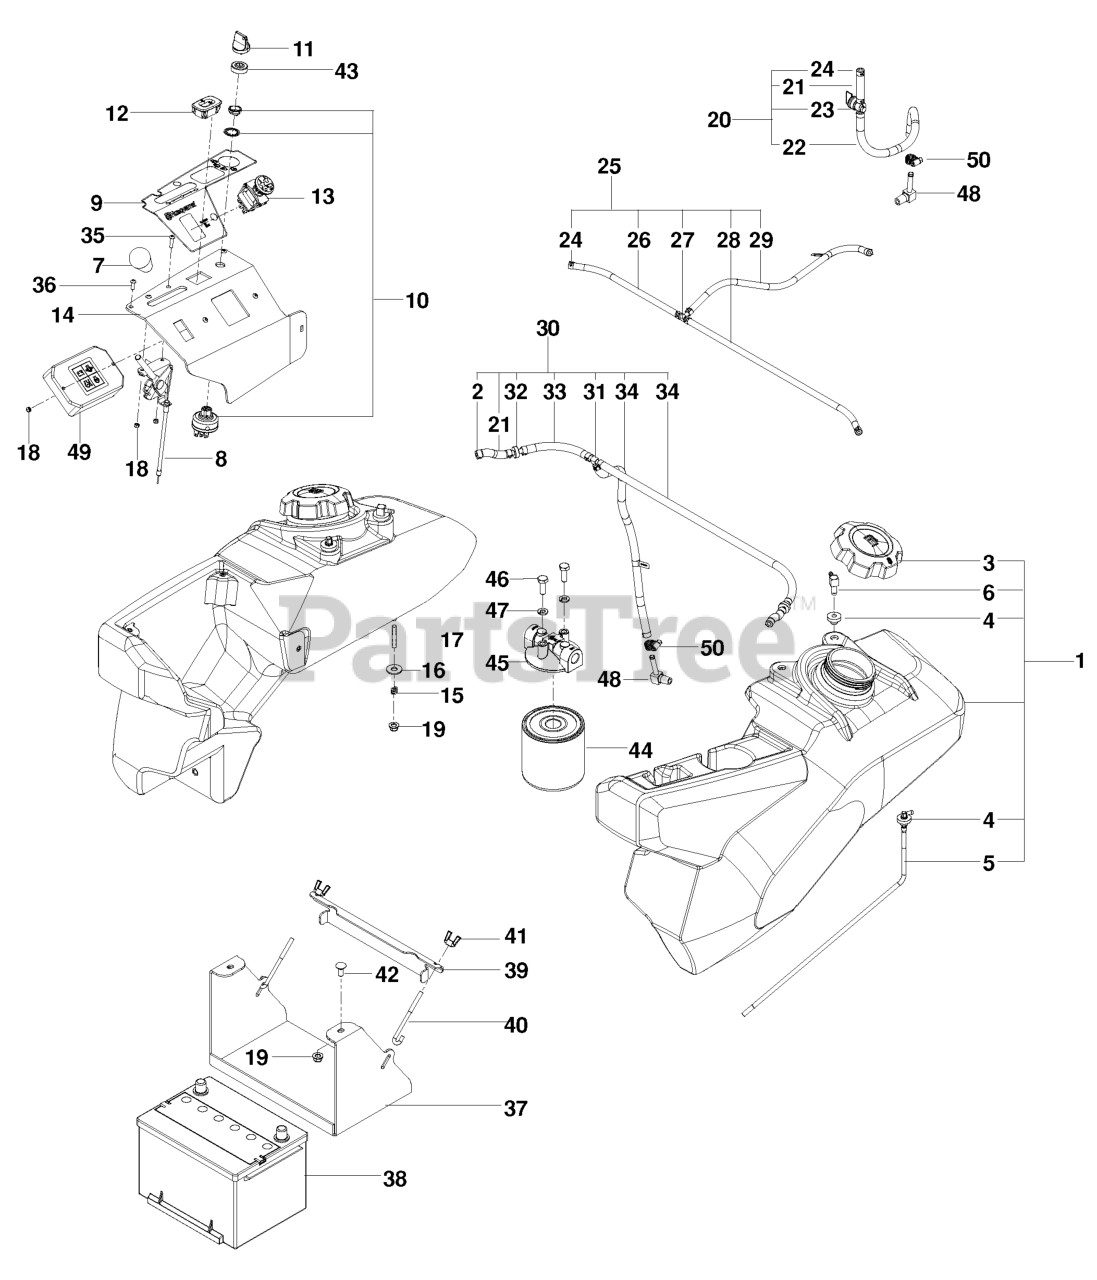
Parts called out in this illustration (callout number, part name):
1	FUEL TANK LT DIESEL
2	CLAMP, HOSE
3	CAP, DIESEL FUEL
4	RUBBER GROMMET
5	FITTING, FUEL
6	FITTING, RETURN, 90
7	KNOB - SHIFT
8	CABLE, THROTTLE, DIESEL
9	DECAL, CONTROL, DIESEL
10	SWITCH, IGNITION, INDAK
11	KEY, IGNITION
12	HOUR METER
13	SWITCH, PTO 10 AMP
14	PANEL, CONTROL, DIESEL-GRAY
16	FLAT WASHER 5/16 SAE
17	STUD, 5/16C
18	NUT 10-24 NYLOC
19	5/16-18 NYLOC FLANGE NUT
20	LINE, FUEL ASSEMBLY
21	FUEL LINE 3"
22	FUEL LINE 14"
23	FUEL VALVE
24	HOSE CLAMP
25	ASSEMBLY, FUEL LINE, RETURN
26	HOSE, FUEL, 3/16" X 9-1/2"
27	TEE, FUEL LINE 3/16"
28	HOSE, FUEL, 3/16" X 17-1/4"
29	HOSE, FUEL, 3/16" X 18-1/2"
30	ASSEMBLY, FUEL LINE
31	TEE, FUEL LINE, .25
32	VALVE, CHECK, .25
33	FUEL LINE 5"
34	HOSE, FUEL 1/4" X 21"
35	SCR #10-24 X .75 SKT HD BLK
36	SCR #10-24 X 3/8 SKT HD BLK OX
37	BOX, BATTERY, BLK
38	BATTERY, 500 CCA
39	BRACKET, BATTERY MOUNT
40	HOOK, "J"
41	WING NUT 1/4
42	BOLT 5/16C X 3/4" CARRIAGE
43	CAP IGNITION NUT
44	FILTER, FUEL
45	HEAD, FUEL FILTER
46	HCS 1/4C X 3/4 HCS
47	LOCKWASHER 1/4"
48	FITTING, FUEL, 90
49	MODULE, CONTROL
50	CLAMP, WORM GEAR, NO. 4
